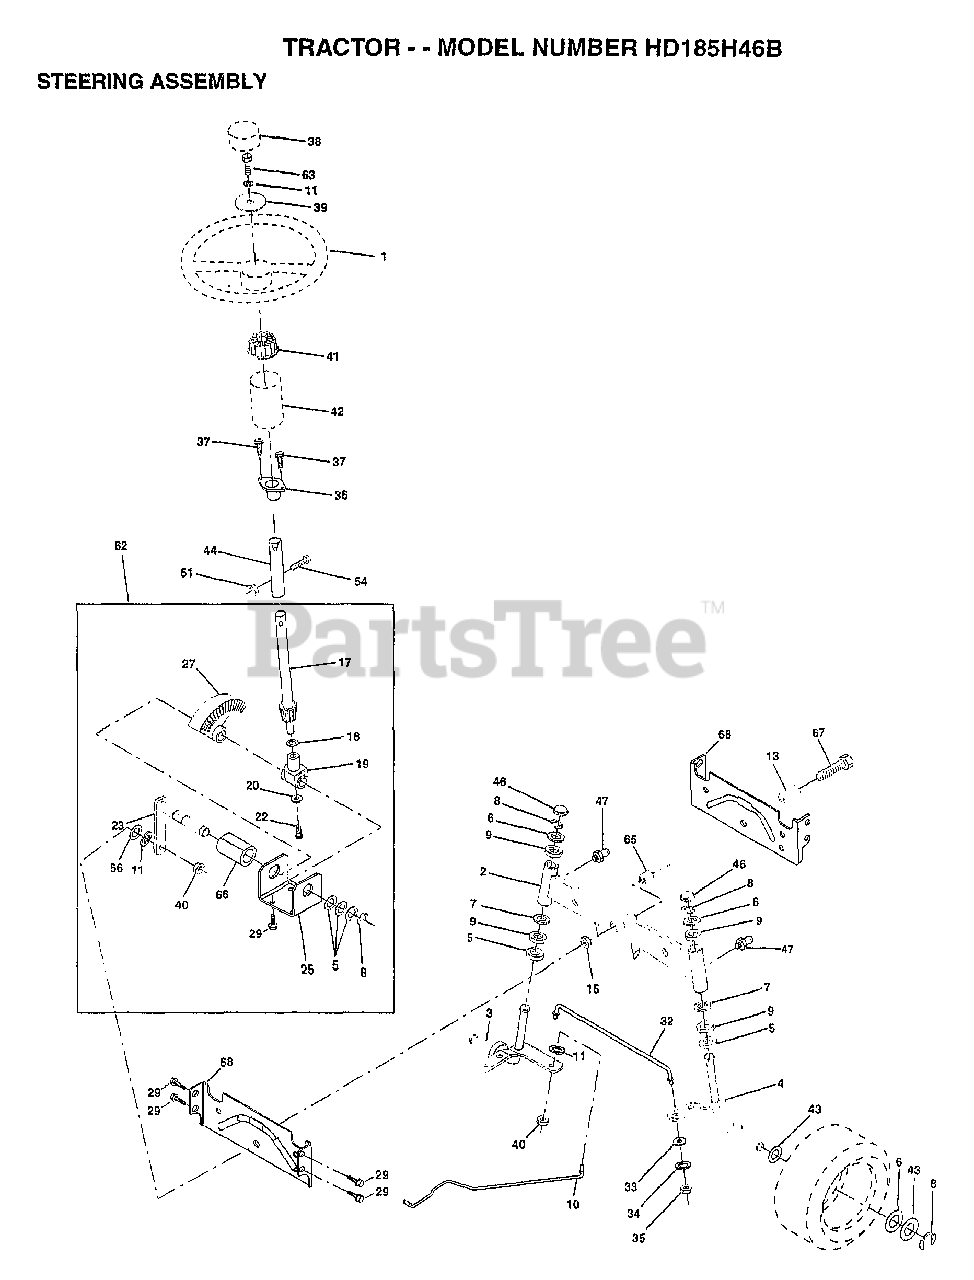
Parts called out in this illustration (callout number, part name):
1	WHEEL STR AYP BLK
2	AXLE ASM
3	"SPINDLE ASM,RH"
4	"SPINDLE AMS,LH"
5	WASHER .T
6	WASHER
7	WASHER
8	RING
9	COL. SRTG. BEAR.
10	DRAGLINK-STAMPED
11	LOCKWASHER
13	BEARING AXLE
15	"NUT-LOC,FLANGE LT"
17	SHAFT ASM STEERIN
18	THRUST WASHER
19	SUPPORT.SHAFT
22	SCREW HEX SOC1/4-
25	BRKT-STEERING
27	GEAR SECTOR
29	SCREW
32	ROD.TIE.19.75
33	WASHER M
34	LOCKWASHER
35	NUT.LOCK.5/16-24
36	BUSHING.STEERING
37	"SCREW-TT,10-32 FL"
38	CAP STEER AYP
39	WASHER T
40	GRIPCO NUT
41	ADAPTER LT
42	BOOT.STEER.PL
43	WASHER
44	EXT SHAFT STEERIN
46	CAP
47	ZERK M
51	NUT
54	BOLT
56	WASHER
62	KIT STEERING ASM
63	BOLT
65	SPACER AXLE
66	"BEARING-ARM,PITMA"
67	BOLT
68	BRACE AXLE
